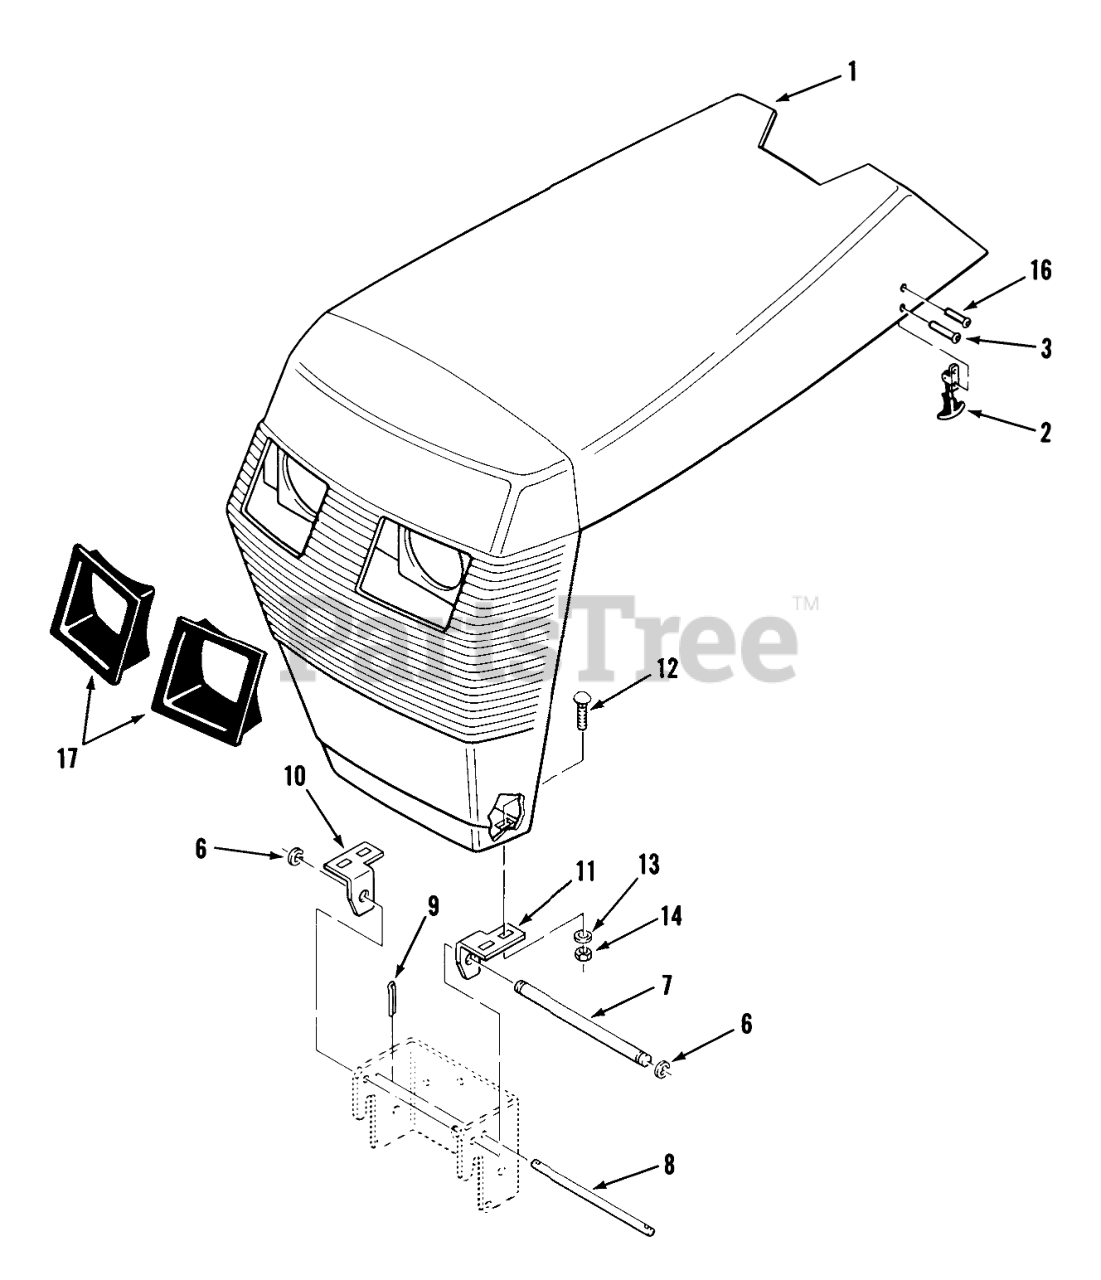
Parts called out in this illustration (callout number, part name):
1	Hood 516, 518 & 520-HC
1	Hood
2	Hood Latch (includes 109236 Handle Ass-y & 109237 Latch Keeper)
3	RIVET -4
6	RING-RETAINING
7	GRILL PIVOT ROD
8	ROD-HOOD STOP
9	Cotter Pin
10	BRKT-GRILL PIVOT R
11	BRKT-GRILL PIVOT R (NS)
12	Bolt-Carriage
14	Nut
16	RIVET
17	HEADLIGHT BEZEL ASSY.(SERVICE)
24	WASHER 5/16 SAE
